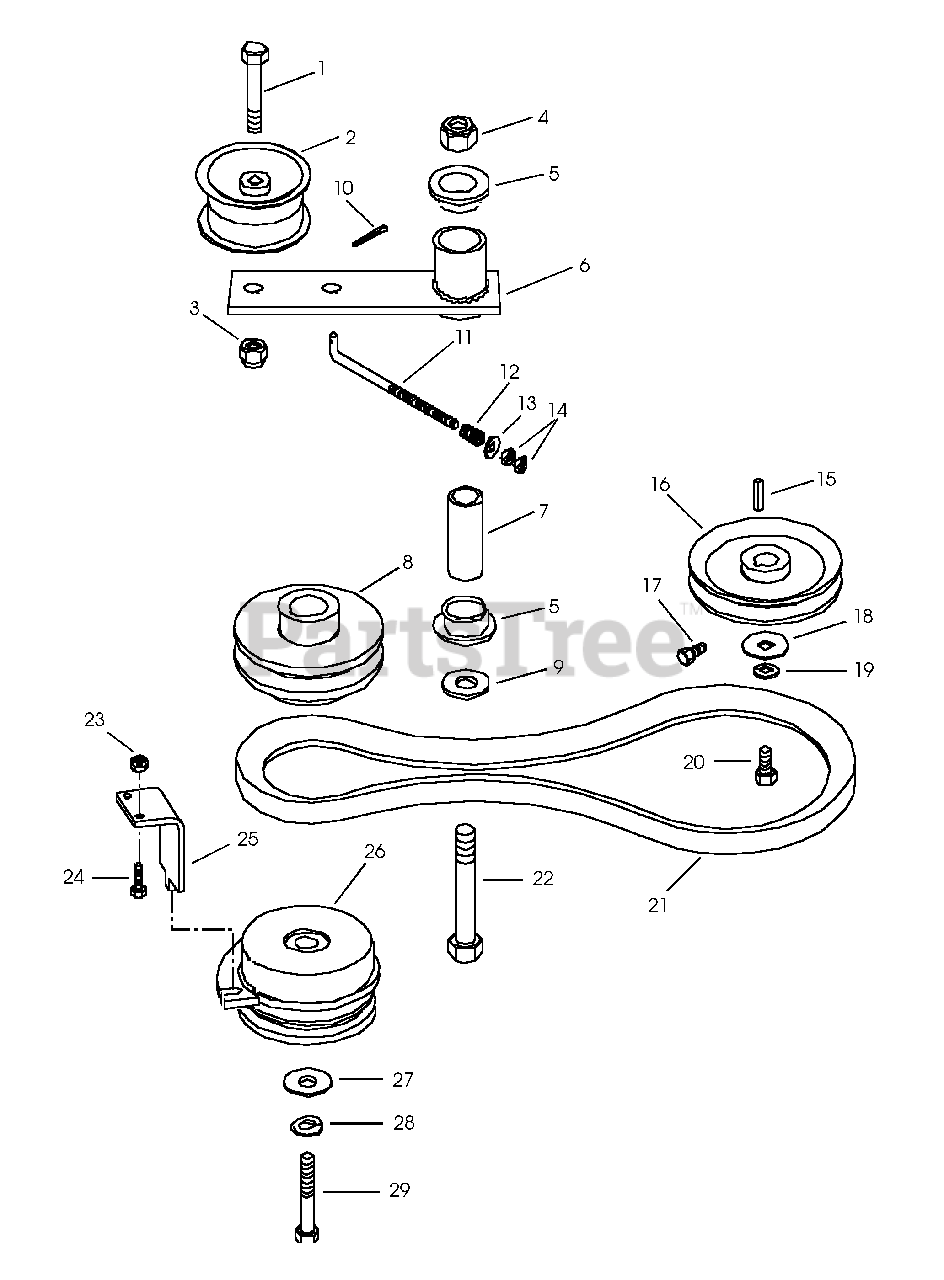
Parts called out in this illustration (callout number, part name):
1	Bolt-Hex .38-16 x 1.75 Grade 5
2	Idler-Pulley Flat 3.25 x .625
3	Nut-Locking-Center .38-16 Grade 2
4	Nut-Locking-Center .50-13 Grade 5
5	Bushing-Flange .762 x 1.0 x .580 x 1.48
6	Weldment-Ground Drive Idler
7	Bushing-Steel .560 x .745 x 2.04
9	Washer-Flat-Steel .531 x 1.06 x .095
10	Pin-Center .09 x .75
11	Rod-Idler
12	Spring-Compression .125 x .78 x 1.00
13	Washer-Flat-Steel .406 x .812 x .065
14	Nut-Jam .375-24
15	Key-Straight 5MM x 25MM x 5MM
16	Sheave 4.0 x .199
17	Bolt-Hex .25-20 x .50 Grade 5
18	Washer-Flat-Steel .25 x 1.0 x .048
19	Washer-Locking .25 x .062
20	Bolt-Hex M6 x 1.0 12
21	V-Belt A-Section 24.50 x .516
22	Bolt-Hex .50-13 x 3.00 Grade 5
23	Nut-Locking-Center .31-18
24	Bolt-Hex .31-18 x .75 Grade 5
25	Clutch Stop
26	Clutch-Electric
27	Washer-Flat-Steel .469 x 2.00 x .25
28	Washer-Locking .44 x .109
29	Bolt-Hex .44-20 x 2.5 0
